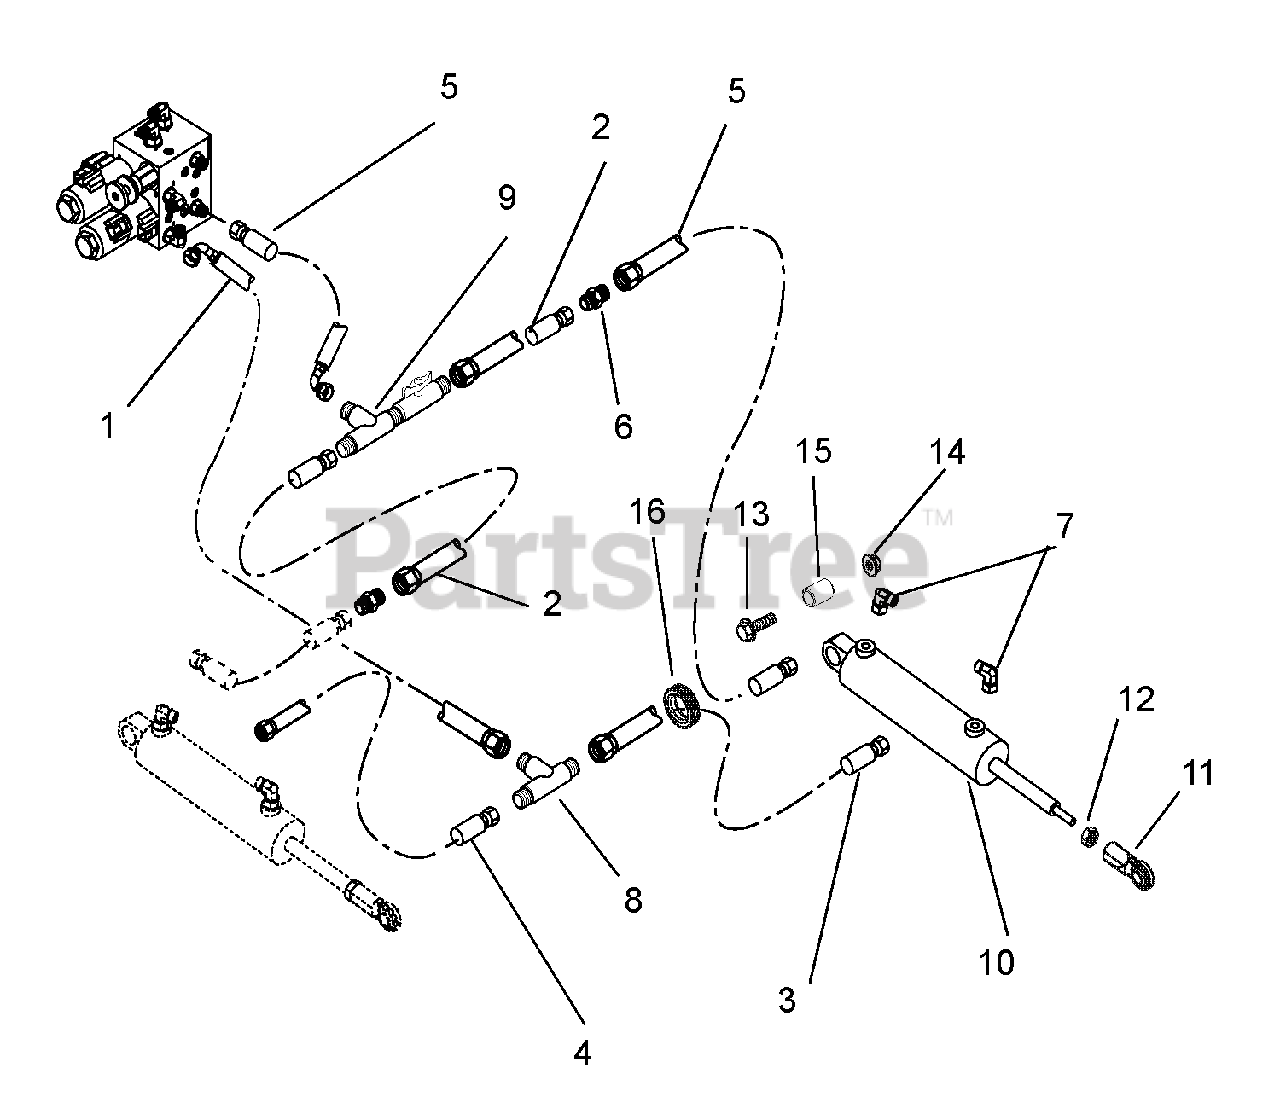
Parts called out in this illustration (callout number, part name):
1	Hose, Hydraulic
2	Hose, Hydraulic
3	Hose, Hydraulic
4	Hose, Hydraulic
5	Hose, Hydraulic
6	Fitting, Hydraulic Bulkhead M4F-M4F
7	Fitting, Hydraulic
8	Fitting, Hydraulic, M4F-M4F-M4F
9	Valve, Hydraulic, M4F-M4F-M4F
10	Cylinder, Hydraulic Deck Lift
11	Rod End, 5/8 RH Female
12	Nut, Jam .625-18
13	Bolt, Hex .50-13 x 2.50 Grade 5
14	Nut, Nyloc Flange .50-13
15	Bushing, .516 x 1.00 x 1.05
16	Grommet, 1.25
